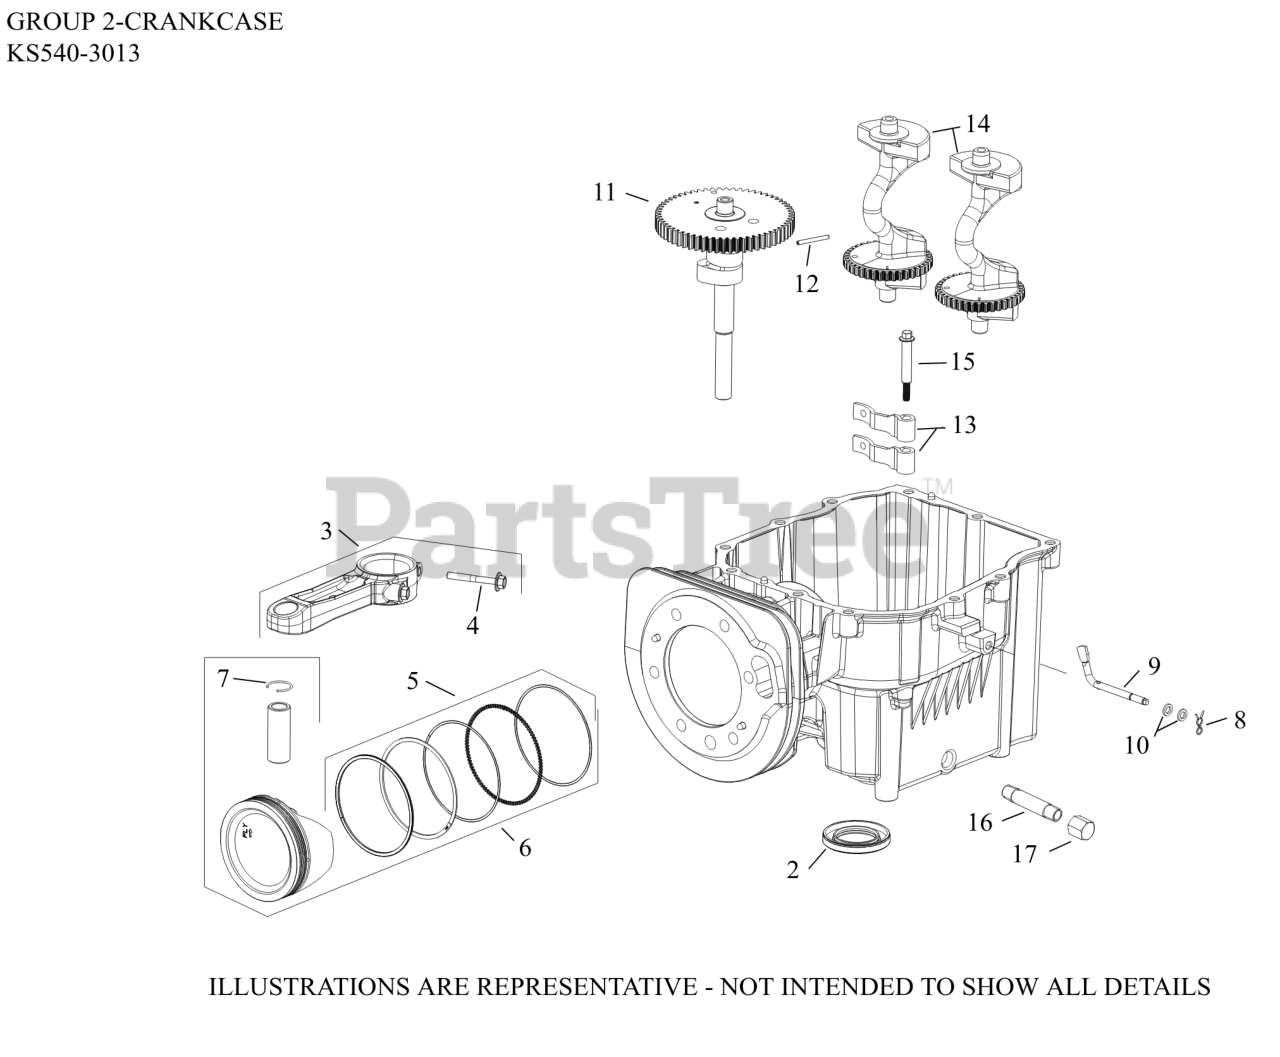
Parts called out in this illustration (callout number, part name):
2	SEAL, OIL
3	ROD, CONNECTING ASSEMBLY
4	SCREW, HEX FLANGE REDUCED BODY (M6 X 47)
5	RING SET (94MM)
6	KIT, PISTON, RINGS, PIN AND CLIPS
7	RETAINER, PISTON PIN
8	CLIP, HITCH PIN
9	SHAFT, GOVERNOR CROSS
10	WASHER, FLAT 6 MM
11	CAMSHAFT ASSEMBLY
13	LEVER, CAM
14	SHAFT, PRIMARY BALANCE
15	SCREW, HEX FLANGE SHOULDER (M6)
NI	NIPPLE, PIPE
NI	CAP, PIPE
